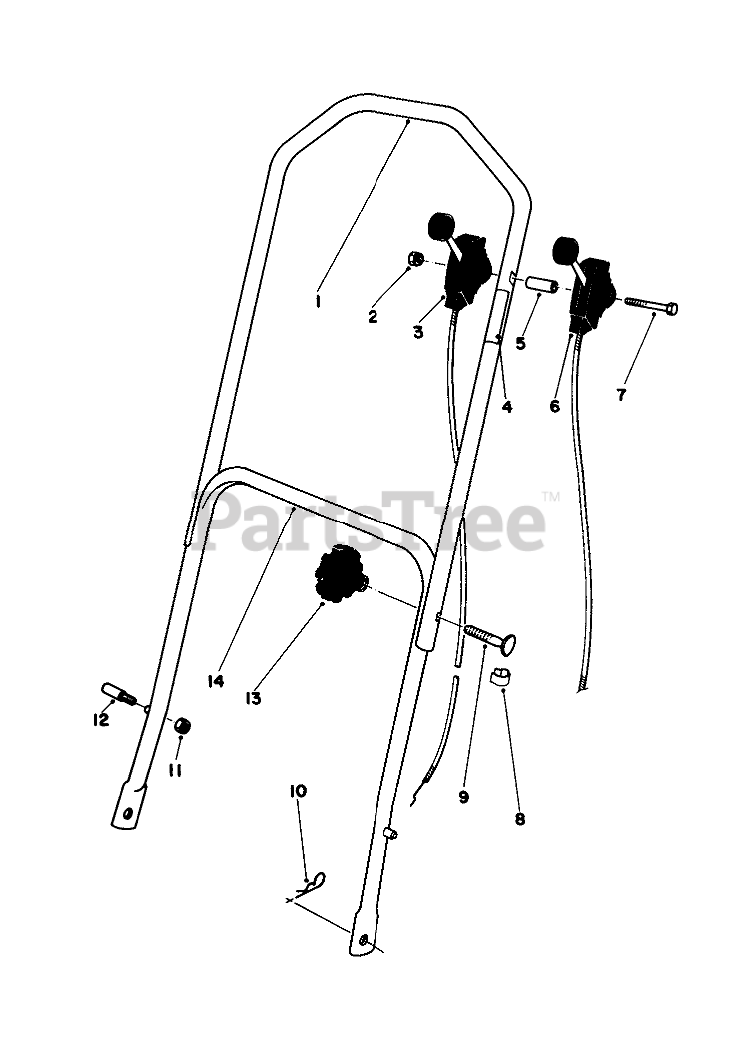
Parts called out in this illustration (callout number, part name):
1	UPPER HANDLE/DECAL
2	NUT-LOCK, NI
3	SERVICE THROTTLE CONTRO
4	Decal-Throttle & Traction
5	Spacer
6	SERVICE TRACT. CONTROL
7	SCREW-HH
9	5/16-18 X 2 HNDLE SCREW
10	PIN-COTTER, HAIR
11	Locknut
12	HANDLE PIN
14	LOWER HANDLE ASM
